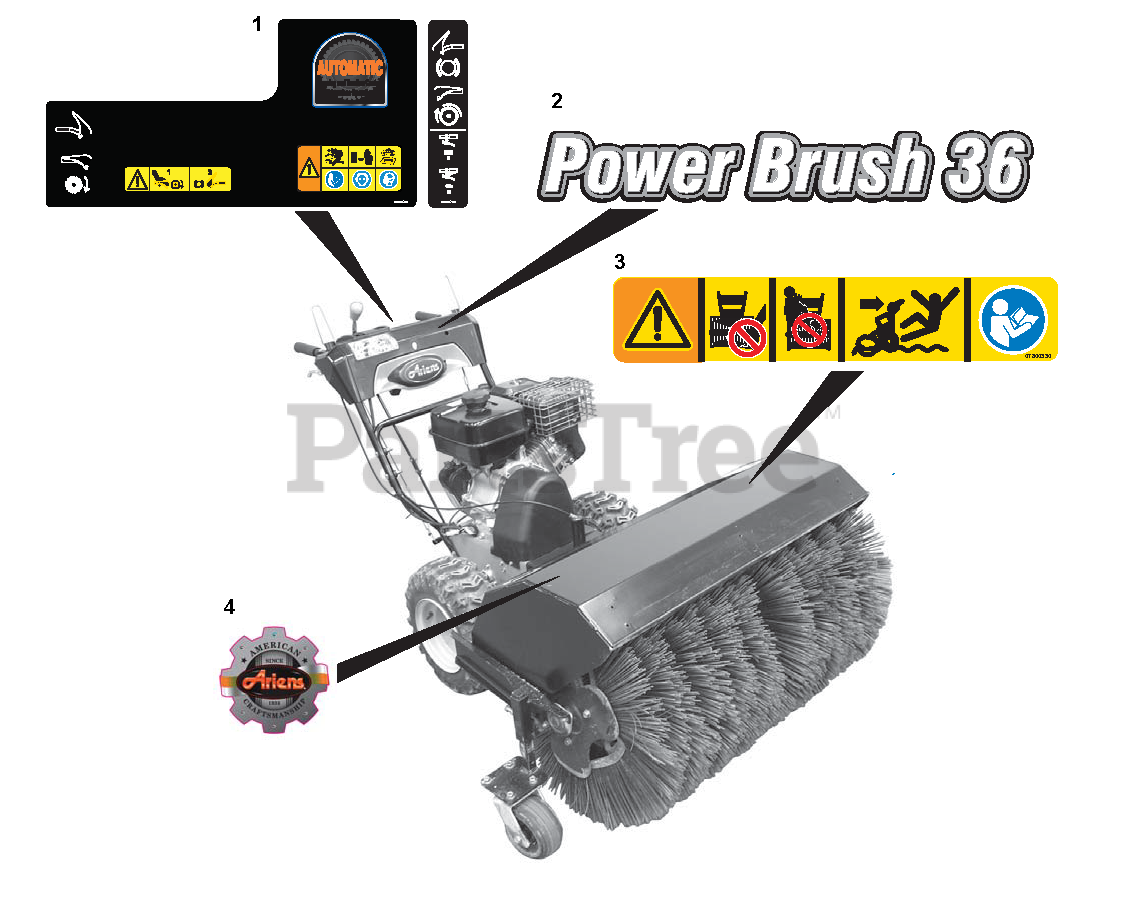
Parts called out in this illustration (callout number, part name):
1	DECAL, CONTROL, LARGE BRUSH
2	DECAL,POWER BRUSH 36",ARIENS
3	DECAL, DANGER -POWER BRUSH-CE
4	Decal, Ariens Heritage
